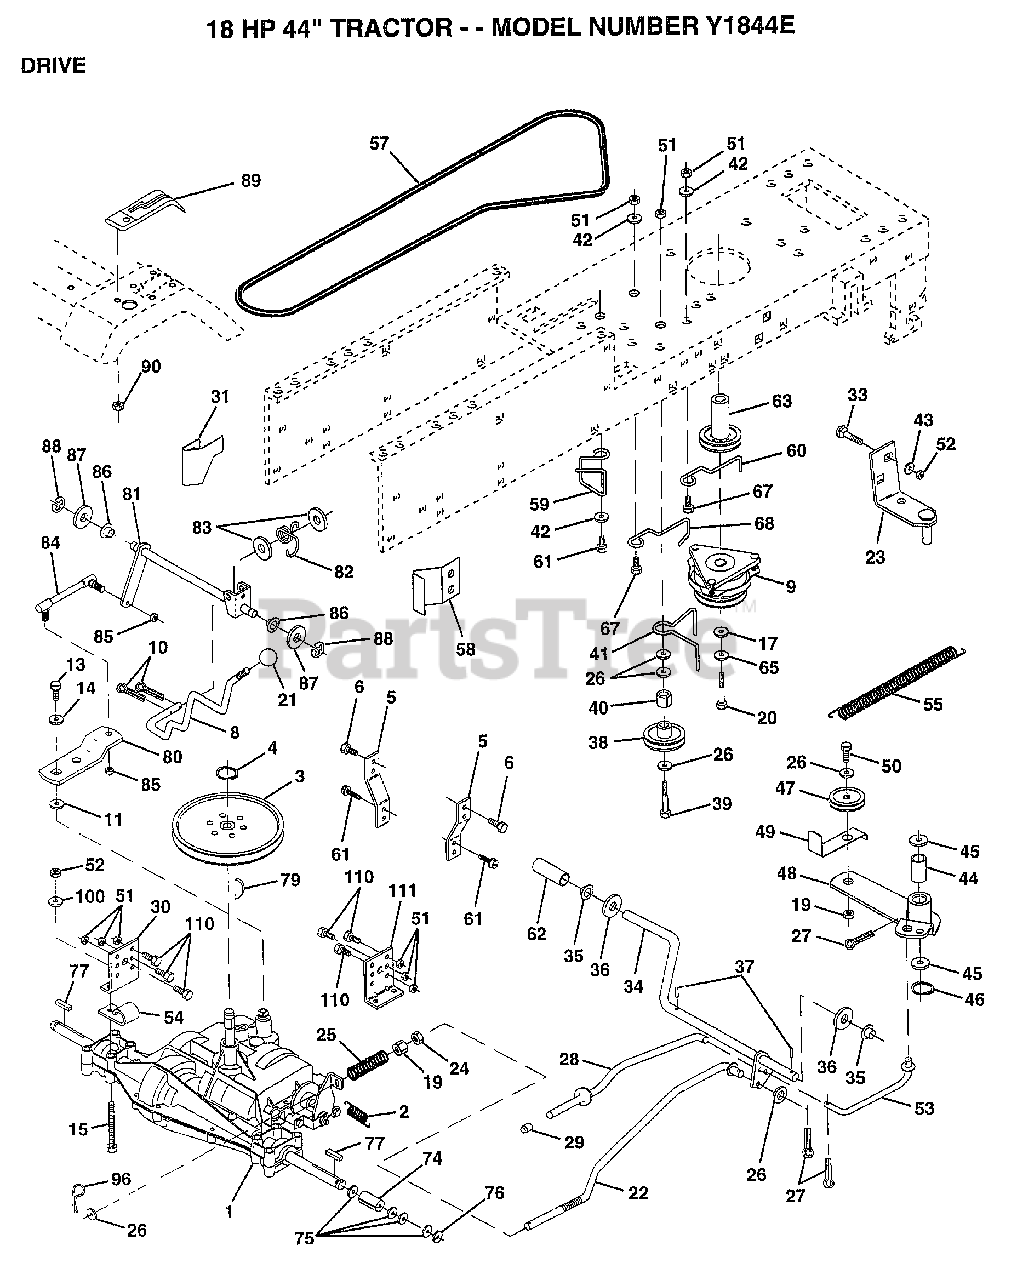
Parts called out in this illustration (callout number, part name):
1	TRANSAX. PRLES.
3	PULLEY TRANSAXLE
4	RING
5	STRAP TORQUE
6	SCREW
10	PIN COTTER 1/8
11	WASH-SHFT PLT LT
13	BOLT.1/4-28.W/PAT
14	WASHER PM
15	BOLT HEX
16	NUT
17	WASHER
19	NUT
21	KNOB T (1/2-HOLE)
22	ROD BRAKE
23	BRACKET.ASM.MTG
24	NUT
25	"SPRING,ROD BRAKE"
26	WASHER
27	COTTER PIN
28	BRAKE PARK ROD
29	PLUNGER CAP T
30	BRKT TRANS LH
31	KEEPER BELT LH
33	BOLT
35	NYLON BEARING
36	WASHER LT
38	PULLEY.IDLER.FLAT
39	BOLT
40	SPACER T
41	BELT KEEPER LT
42	WASHER
43	WASHER T
44	"LY, BEARING"
45	WASHER LT
46	KLIP RING
48	ARM IDLER
49	RETAIN BELT
53	"LINK, CLUTCH T"
54	CLIP T
55	"SPRING, RETURN LT"
57	BELT.GRDRV.94.75
58	"KEEPER,BELT RH"
59	KEEPER BELT CNTSP
60	KEEPER BELT ENGLH
61	SCREW
62	PEDAL COVER T
63	PULLEY ENGINE
65	LOCKWASHER
67	BOLT
68	"KEEPER,BLT ENG LT"
74	SPACER HYT
75	WASHER
76	E RING HYT
77	SQ KEY STD
80	"ARM,SHIFT"
81	"SHAFT,SHIFTER"
82	"SPRING,TORSION"
83	WASHER
84	"ROD,TIE "
85	NUT 1/4-28
86	BUSHING
87	WASHER D
88	KLIP RING
89	CONSOLE SHIFTER
90	NUT
96	RETAINER M
100	WASHER M
111	BRKT TRANS RH
